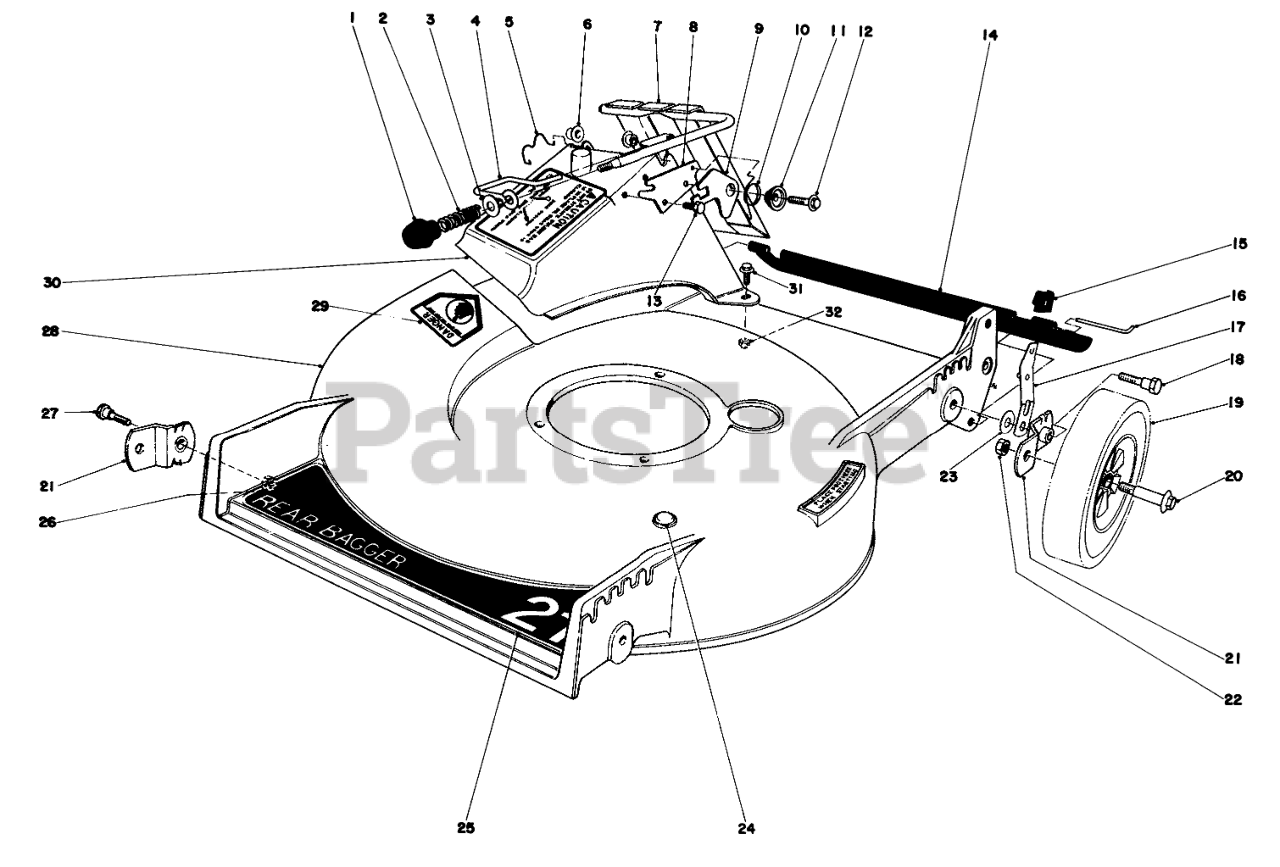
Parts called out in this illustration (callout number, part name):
2	COMPRESSION SPRING
3	WASHER
4	DOOR LATCH
5	DOOR RETAINER
6	BUSHING-NYLON
7	DOOR & HANDLE WA
8	DOOR LATCH PLATE
9	SAFETY LATCH
10	TORSION SPRING
11	Latch Spacer
12	Screw
13	SCREW-HWH
14	SHIELD - TRAILING
15	KNOB-ARM
16	Rod Shield
17	SPRING ARM ASM (R&S)
18	5/16-18 PIVOT SCREW
19	WHEEL & TIRE ASM
20	BOLT-WHEEL
21	PIVOT ARM ASM A
22	Nut
23	WASHER-PIVOT
25	Decal-Deck
26	Nut
27	PIVOT SCREW
28	Deck
29	DECAL-DANGER
30	DISCHARGE CHUTE B
31	SCREW-HH
32	NUT-LOCK, NI
